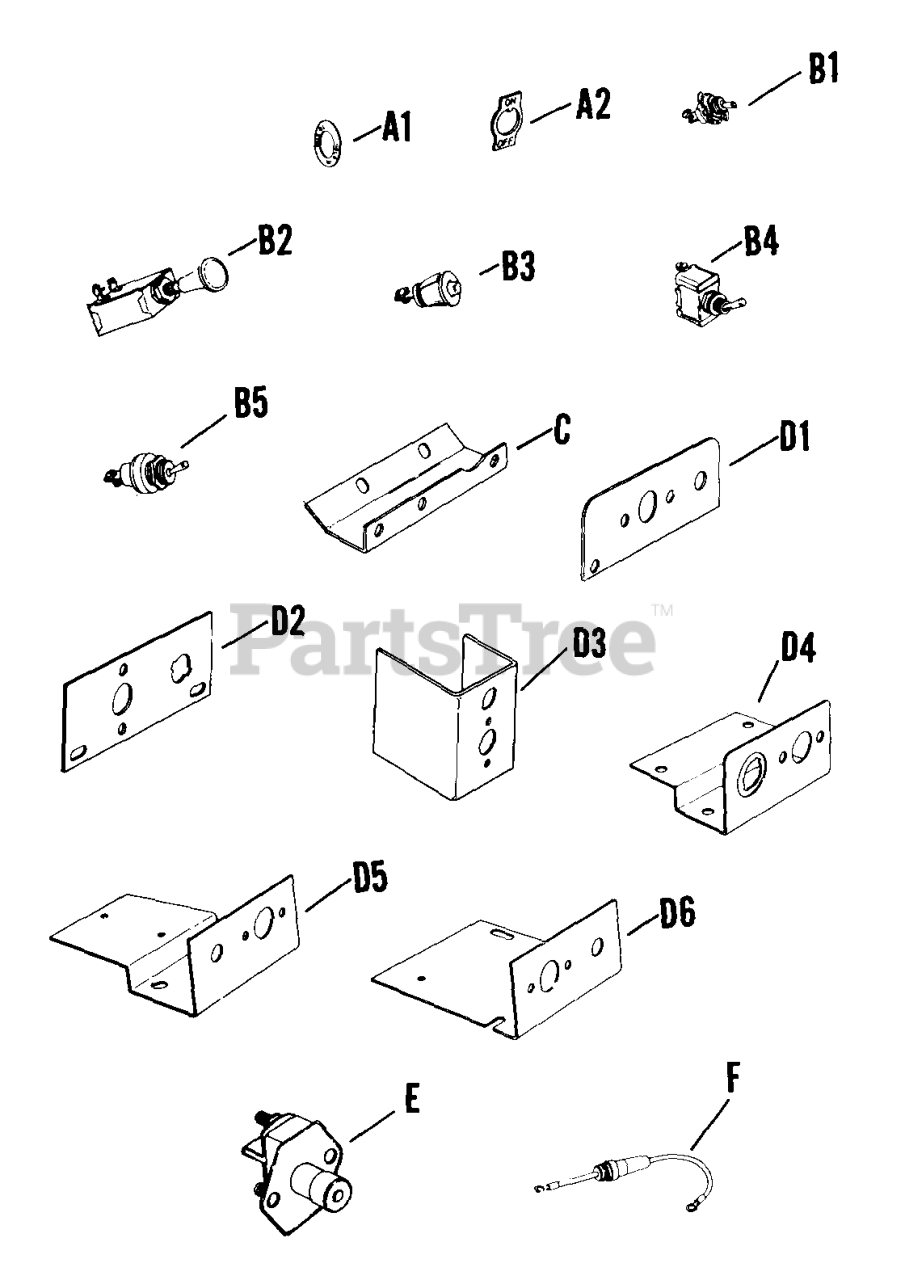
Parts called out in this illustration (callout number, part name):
A2	PLATE - DISCONTINUED
B4	SWITCH - DISCONTINUED
D5	PANEL - DISCONTINUED
E	SWITCH - USE 237851
